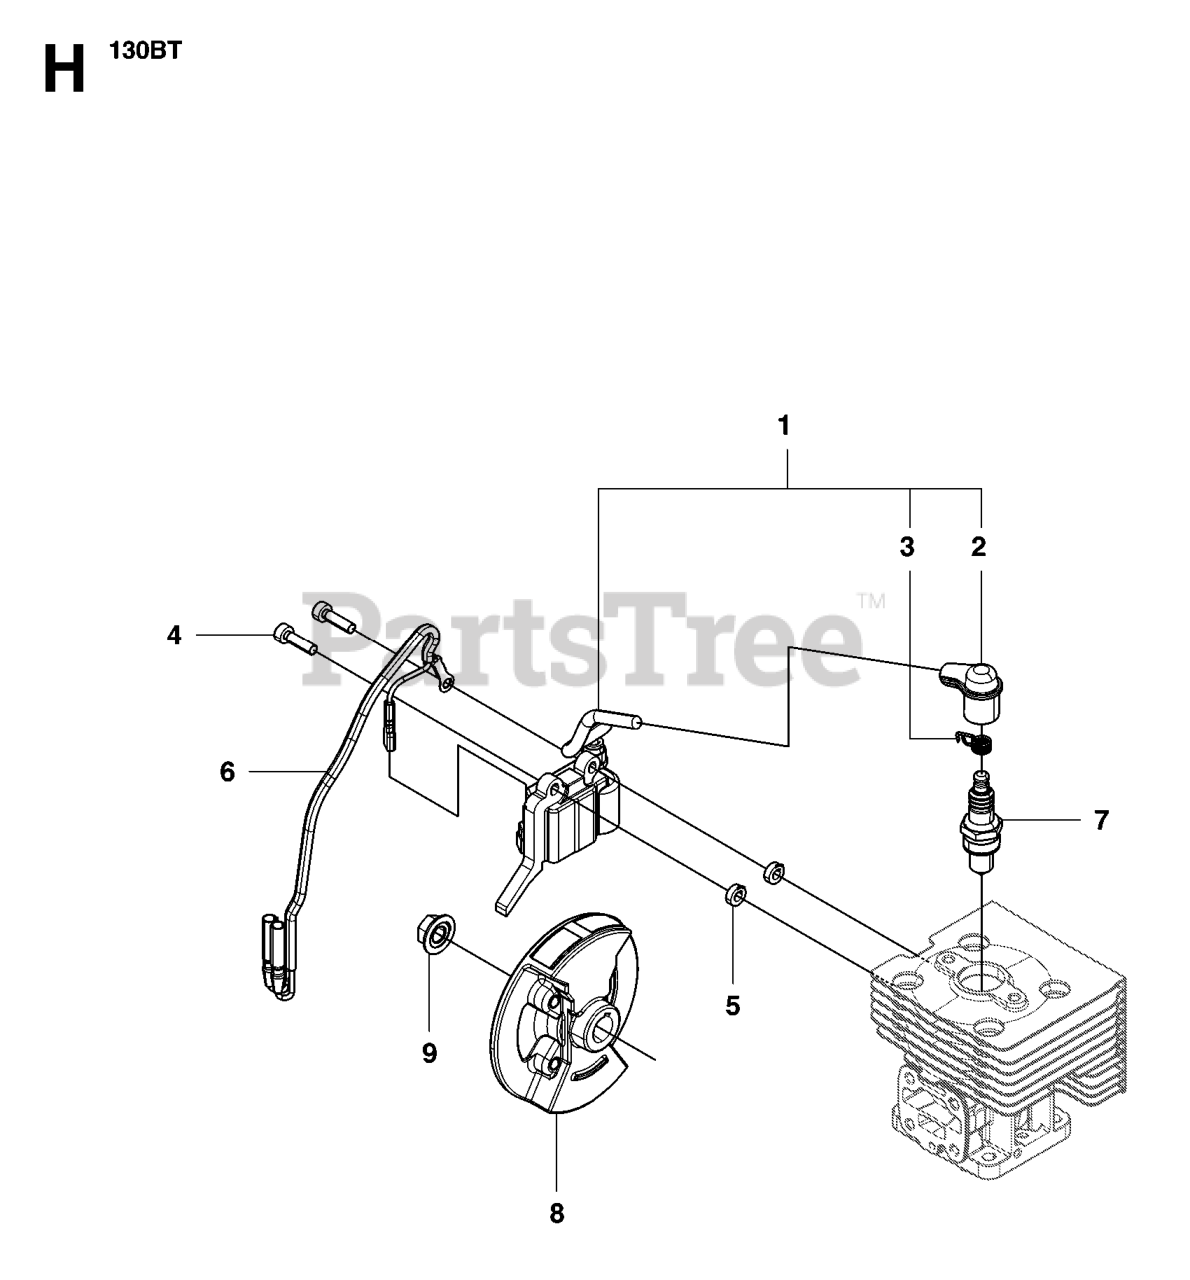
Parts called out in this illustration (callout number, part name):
2	CAP
3	SPRING
4	BOLT
6	CORD-COMPL.
7	SPARKPLUG NGK CMR7H
9	NUT
